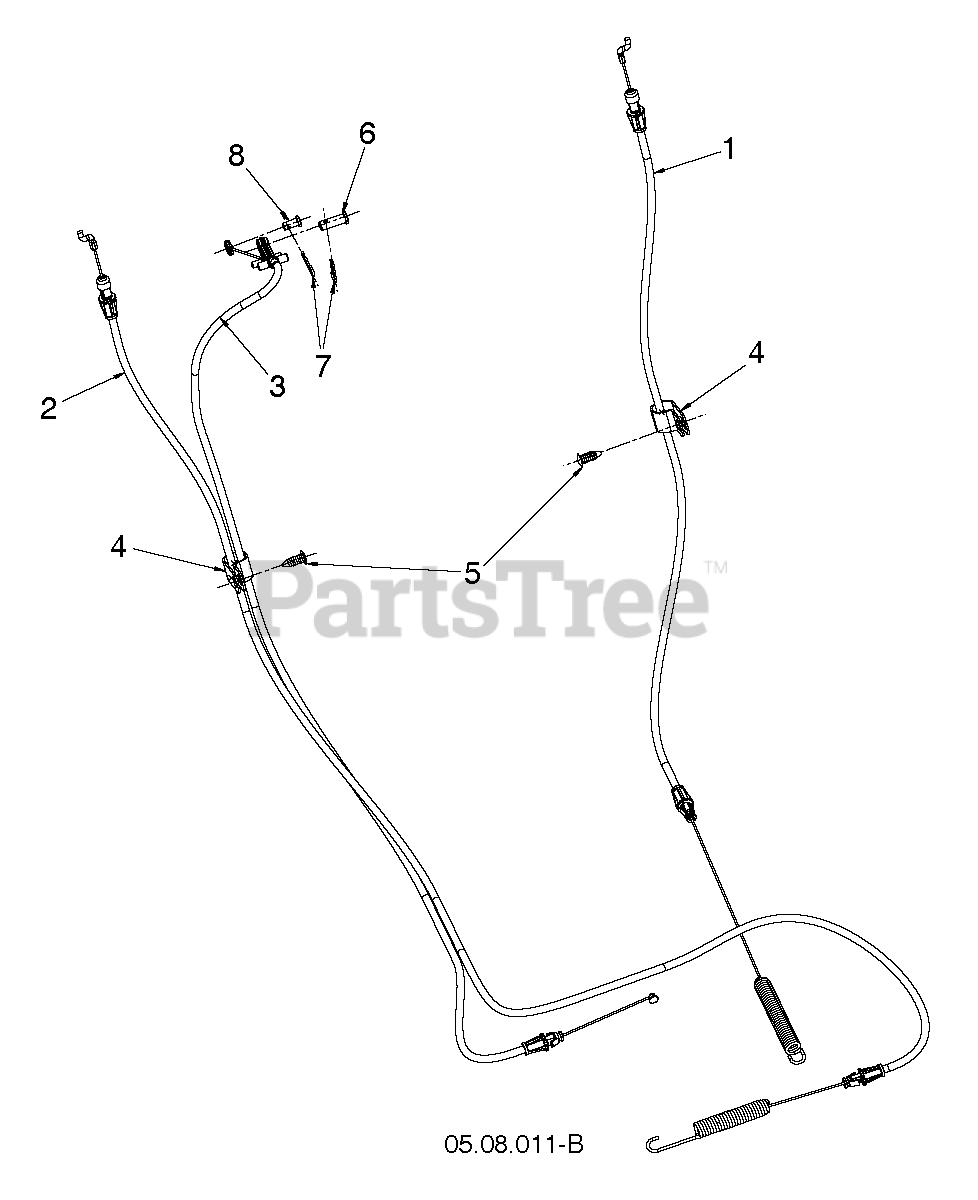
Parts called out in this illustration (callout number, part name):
1	Drive Control Cable, 16
2	Auger Control Cable
3	Speed Control Cable, DSST OPP
4	CLIP.CABLE.BLK
5	FASTENER.PUSH.O.250X0.783
6	Clevis Pin, 5/16 X .875
8	Clevis Pin, .25 X .31
